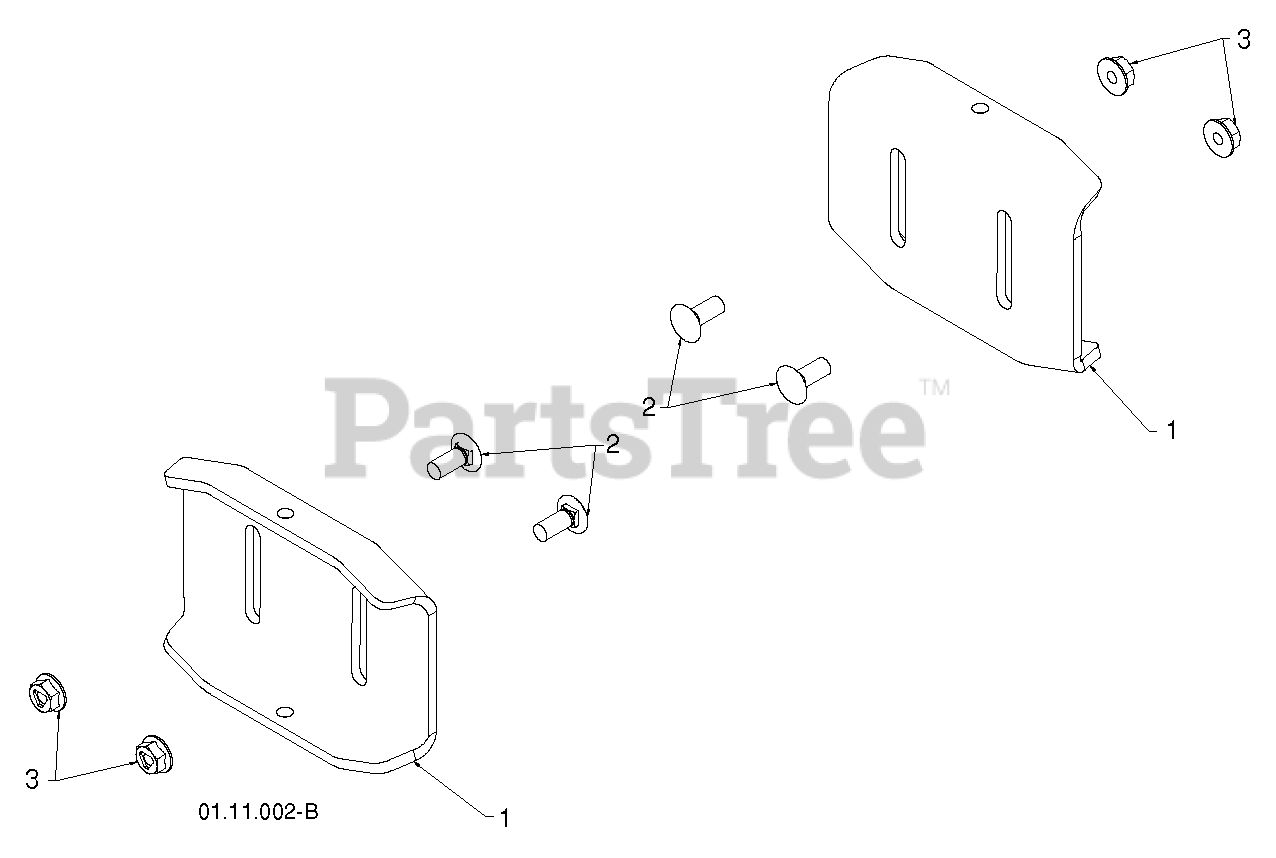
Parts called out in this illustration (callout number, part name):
1	SKID PLATE
2	BOLT
3	NUTNYLOK.FLRANGE.5/16-18
